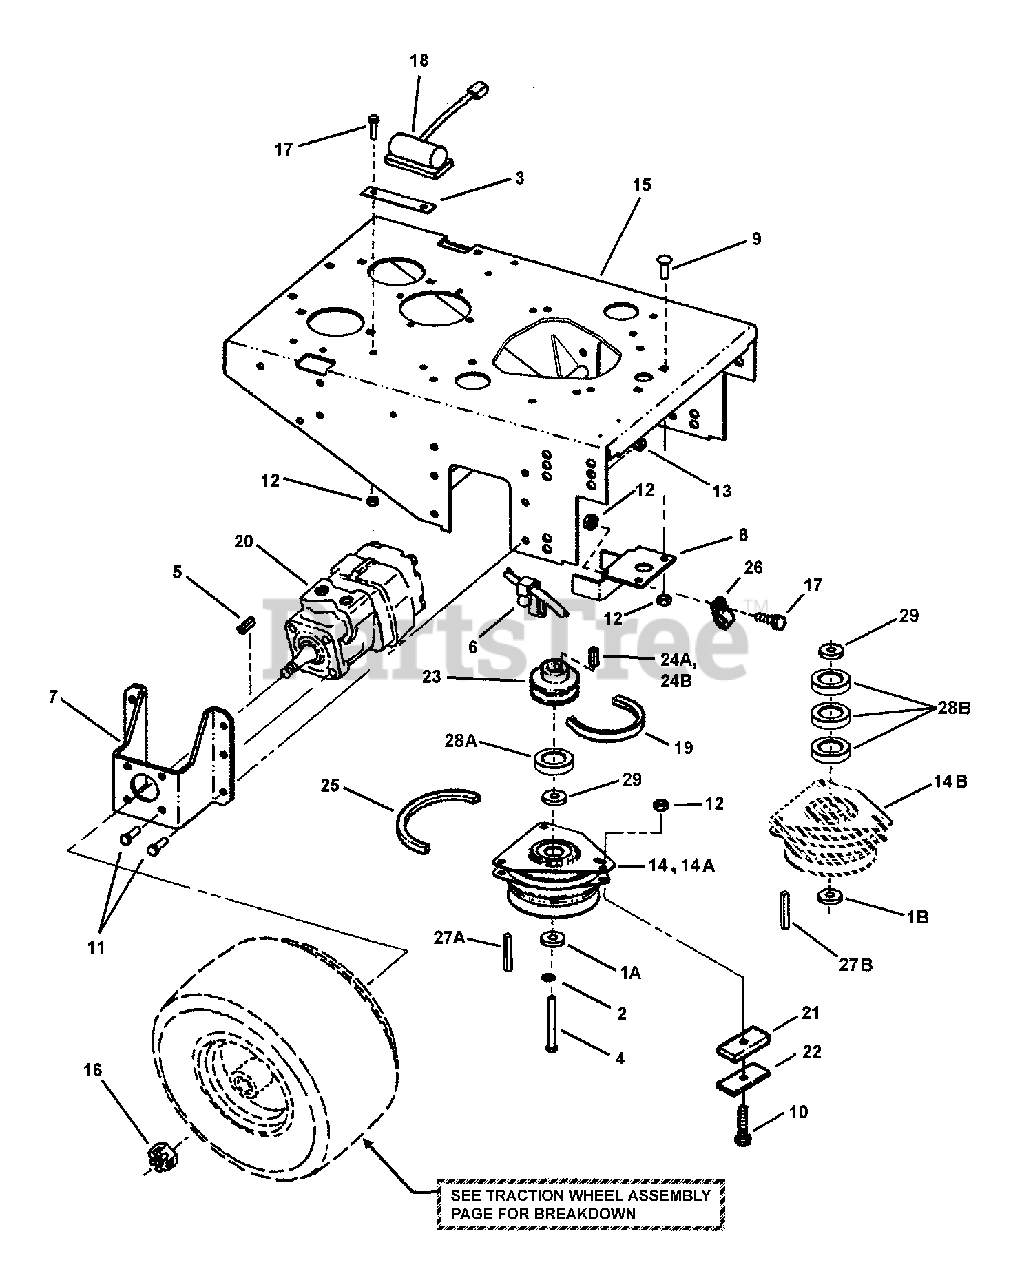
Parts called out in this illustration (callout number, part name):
1A	WASHER, .468 x 1.38 x .25 Flat
1B	SPACER, Clutch
2	WASHER, 7/16" Split Lock
3	BRACKET, Capacitor
4	SCREW, M10-1.5 x 65mm Hex Head Cap
4	BOLT, 7/16-20 X 3" GD5
4	SCREW, 7/16-20 x 2-1/2" Hex Head Cap, GR 5
5	KEY, 3/16" Square x 3/4"
6	CLIP, Harness (for battery drain hose)
7	BRACKET, Wheel
8	BRACKET, Clutch
9	BOLT, 5/16-18 x 1" Short Neck Carriage, GR 5
10	BOLT, 5/16-18 X 1-1/4 GD5 YZ
11	BOLT, 3/8-16 X 1" GD5 CZ
12	NUT, 5/16-18 Hex Top Lock, GR B
13	NUT, 3/8-16, HEX TOP LOCK
14	CLUTCH, Electric (Warner)
14A	CLUTCH, Electric (Ogura)
14B	CLUTCH, Electric (Ogura model GT2.5 SN01)
15	DECK, Rear (Weldment)
16	PACK NUT, 3/4-28 UNEF-2A Thread
17	BOLT, 5/16-18 X 3/4 GD5
18	CAPACITOR, Kawasaki Engine
19	V-BELT, HA4950 Engine/Hydro
20	WHEEL MOTOR w/Pack Nut
21	BUMPER, Electric Clutch
22	WASHER, Rectangular Steel
23	PULLEY, 4", Engine/Hydro
24A	KEY, 1/4" Square w/Bevel
24B	KEY, 1/4" Square x 2"
25	* V-BELT, Sect HB, Nom. Eff. Length: 84.80" (Engine/Deck belt)
25	* V-BELT, Sect HB, Nom. Eff. Length: 66.00" (Primary Engine/Deck belt)
25	* V-BELT, Sect HB, Nom. Eff. Length: 67.80" (Engine/Deck belt)
25	* V-BELT, Sect HB, Nom. Eff. Length: 74.00" (Primary Engine/Deck belt)
26	CLIP, Harness
27A	KEY, 1/4" Square x 2-1/2"
27B	KEY, 1/4" Square x 2-1/4"
28A	BUSHING
28B	SPACER,Clutch, Ogura
29	BUSHING, 1" x 14 Ga Machine
